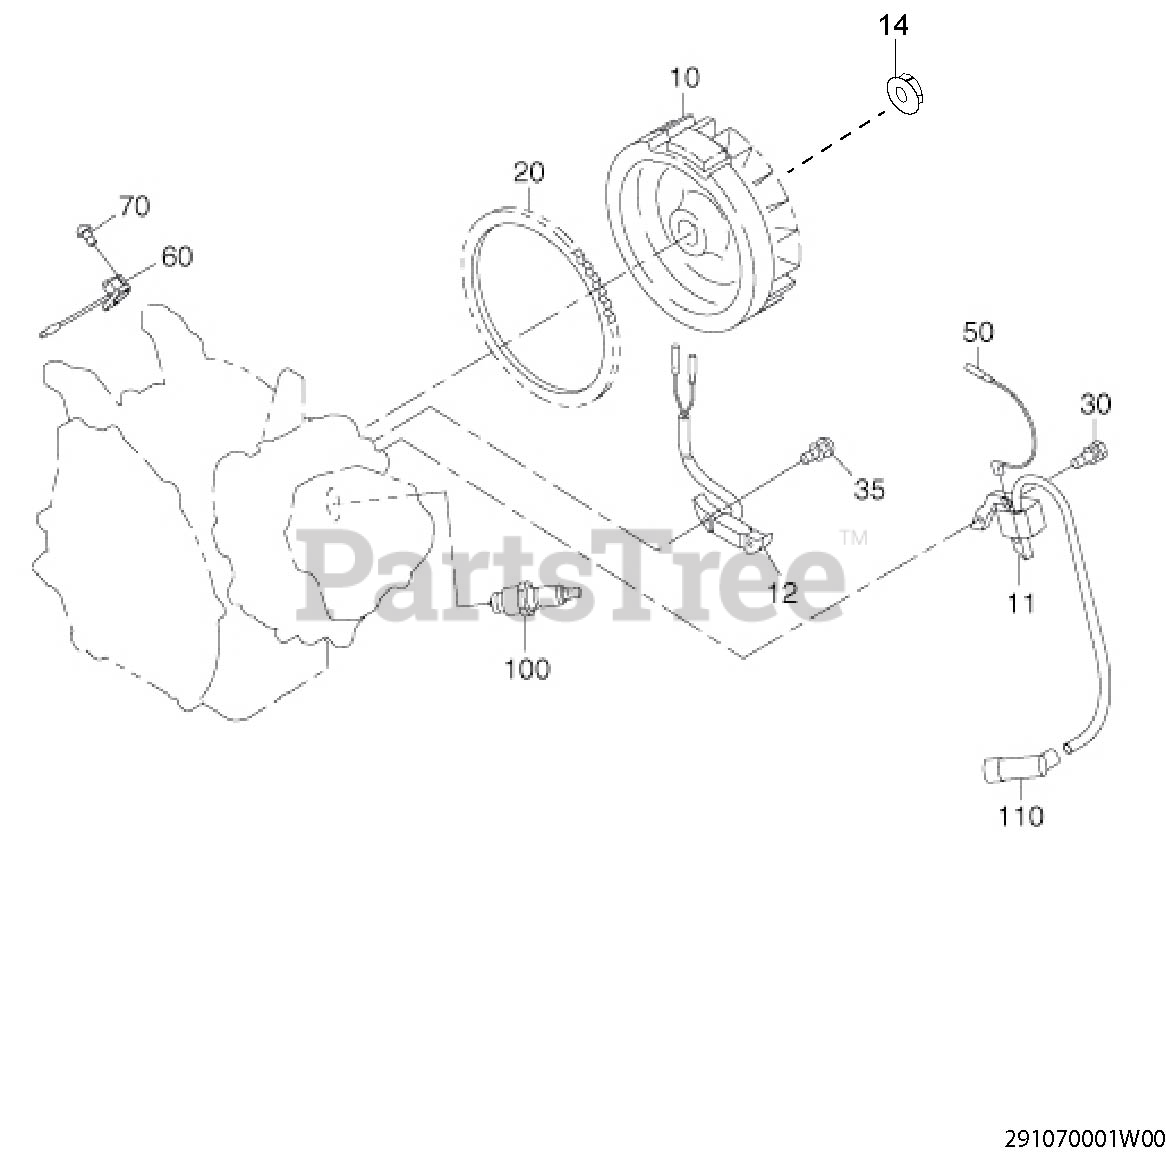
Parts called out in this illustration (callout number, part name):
11	IGNITION COIL CP
30	BOLT AND WASHER
70	TAPPING SCREW
110	SPARK PLUG CAP
